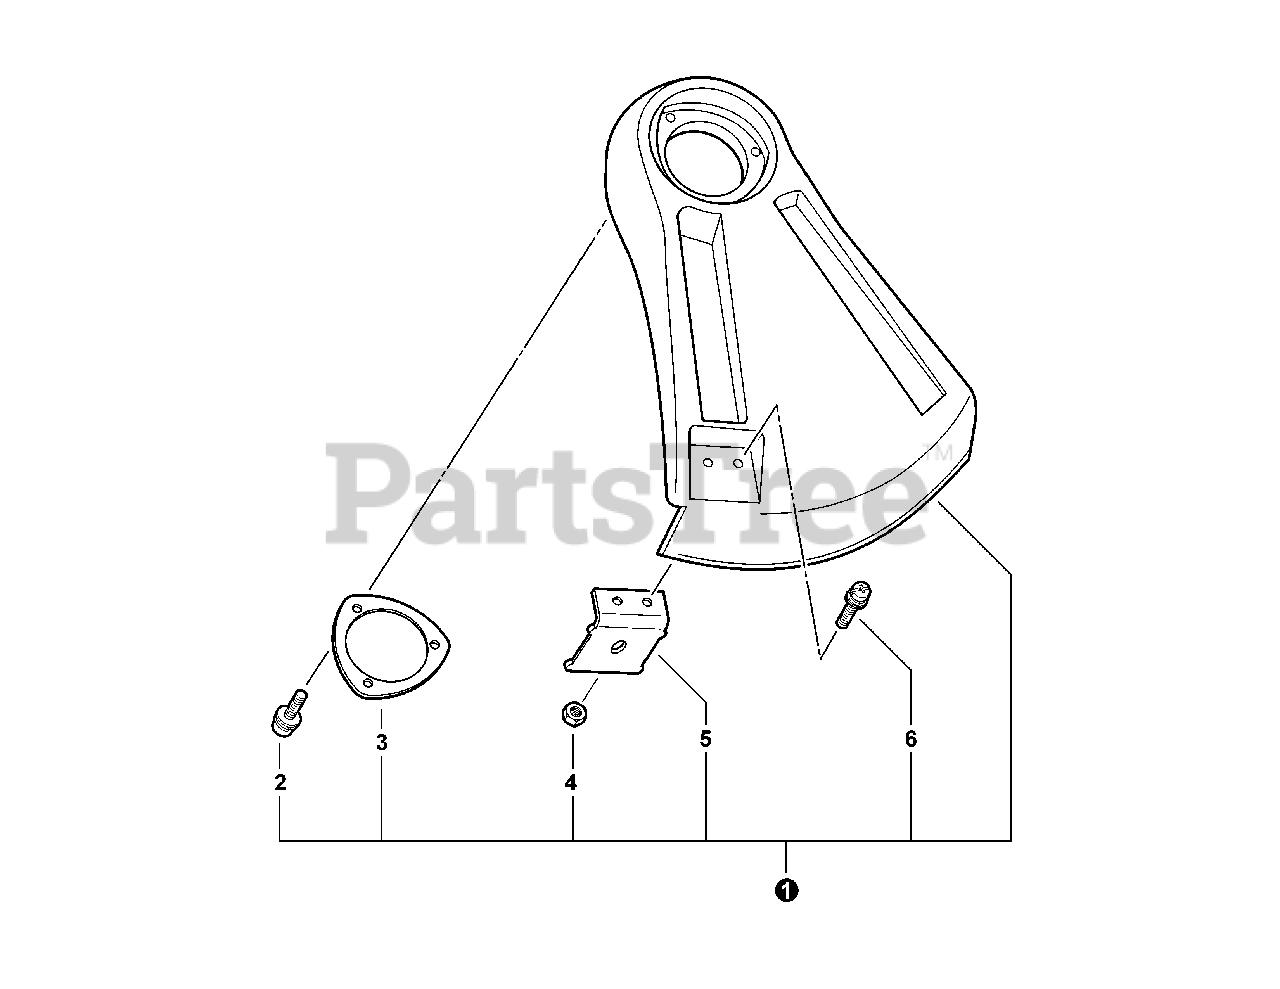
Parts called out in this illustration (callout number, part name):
1	DEBRIS SHIELD KIT
2	BOLT, TORX 5×16
3	PLATE, SHIELD Ø49.5 MM
4	NUT M5
5	CUTTER, LINE
6	BOLT, TORX 5×12
